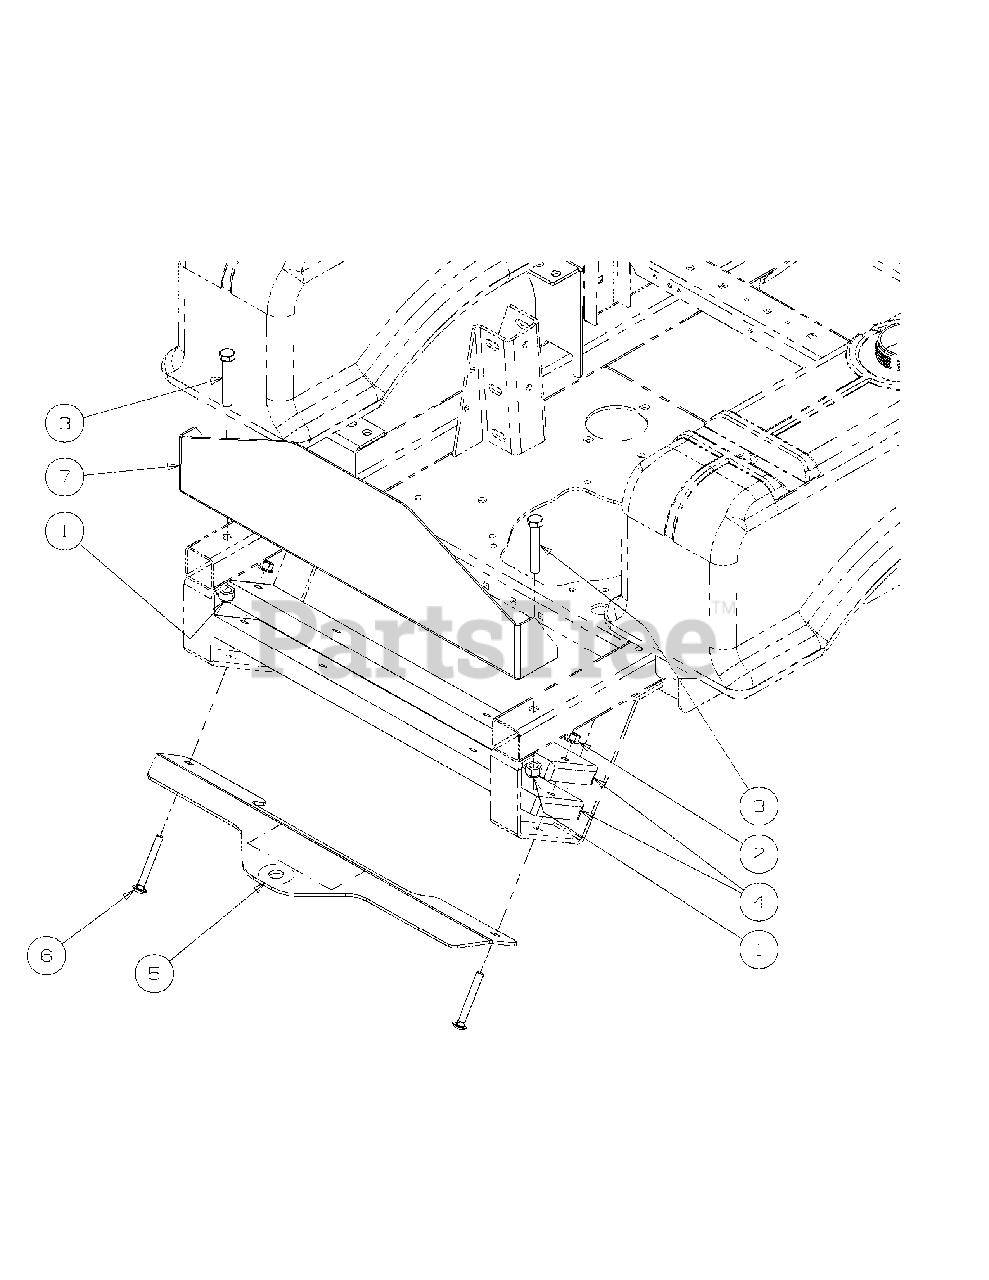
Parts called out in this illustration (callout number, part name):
1	Hex Nut, 1/2-13, Insert Lock
2	Nut, Hex 3/8-16 Flange Lock
3	HHCS, 1/2-13, 3.00
4	Bar, Weight
5	Hitch Bracket
6	Carriage Bolt, 3/8-16 x 3.00
7	Rear Bumper
